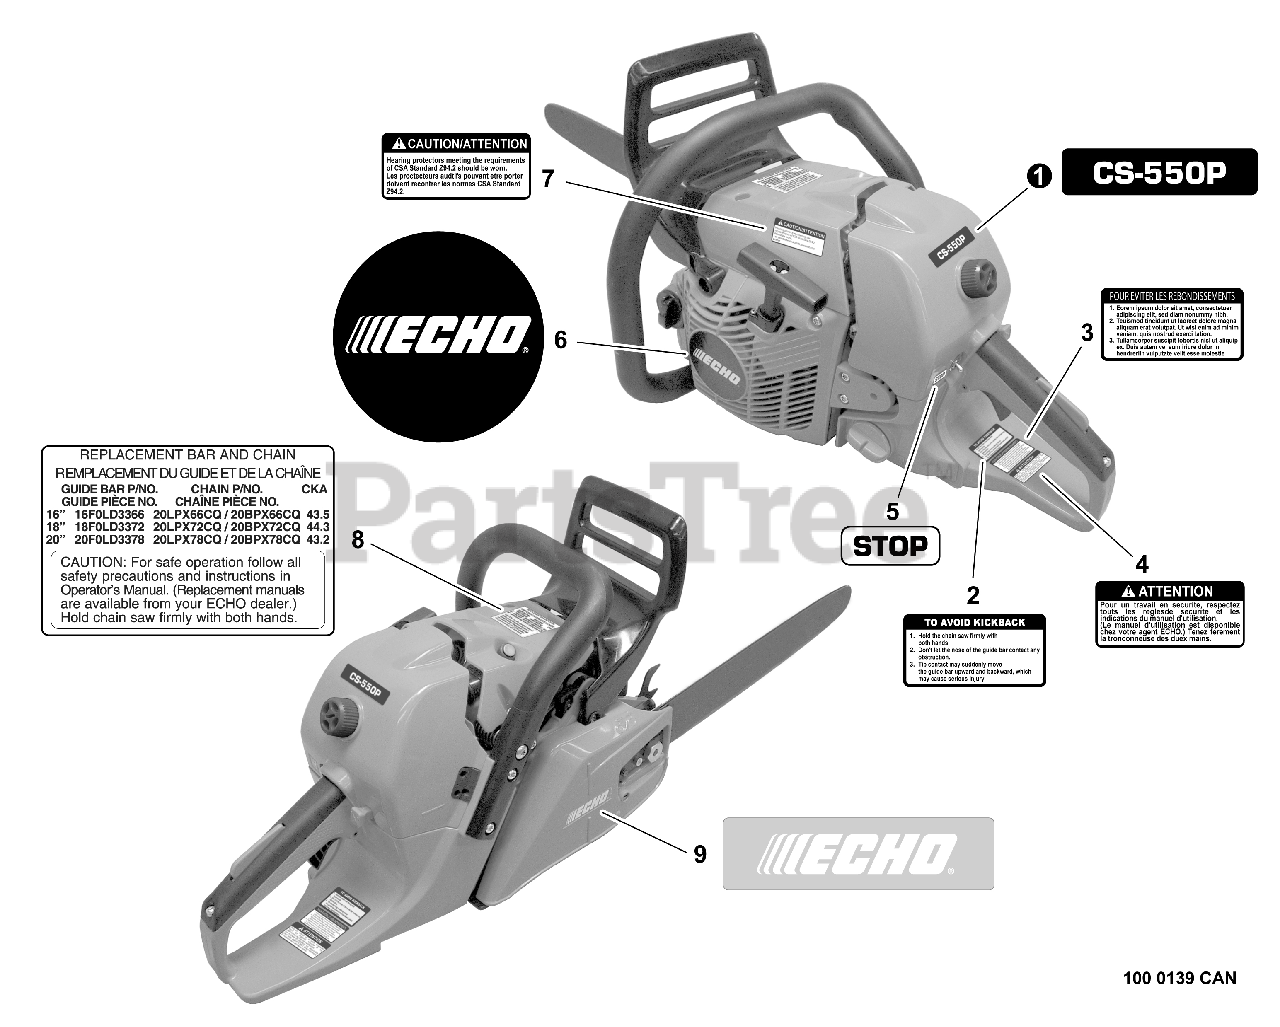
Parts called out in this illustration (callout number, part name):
1	LABEL - MODEL CS-550P
2	LABEL - KICK BACK
3	LABEL - KICK BACK
4	LABEL - ATTENTION
5	LABEL - STOP
6	LABEL - ECHO
7	LABEL - NOISE
8	LABEL - BAR & CHAIN
9	LABEL - ECHO
